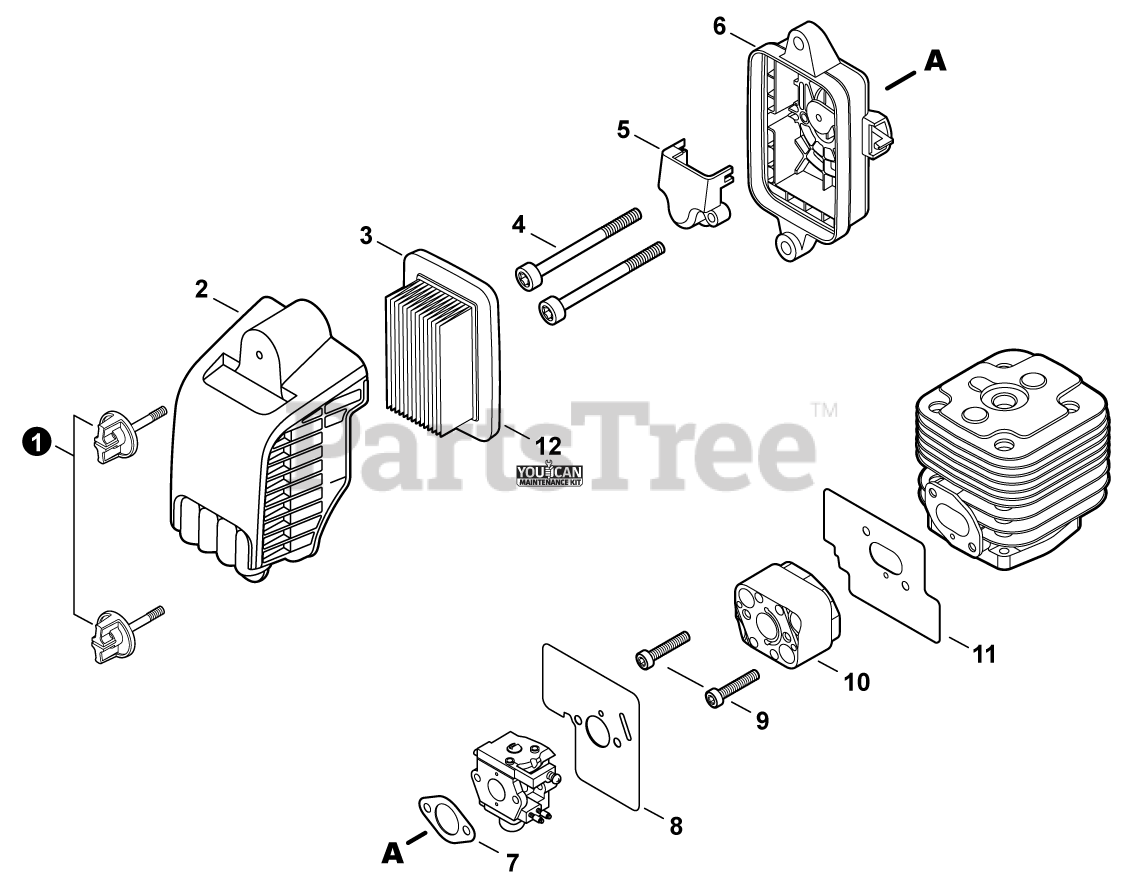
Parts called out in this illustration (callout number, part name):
1	KNOB, FASTENER
2	COVER, AIR FILTER
3	FILTER, AIR
4	BOLT, TORX 5x60
5	PLATE, PREVENT
6	CASE, AIR FILTER
7	GASKET, INTAKE
8	GASKET, INTAKE
9	BOLT, TORX 5x25
10	INSULATOR, INTAKE
11	HEAT SHIELD, INTAKE
12	TUNE-UP KIT - YOUCANT
